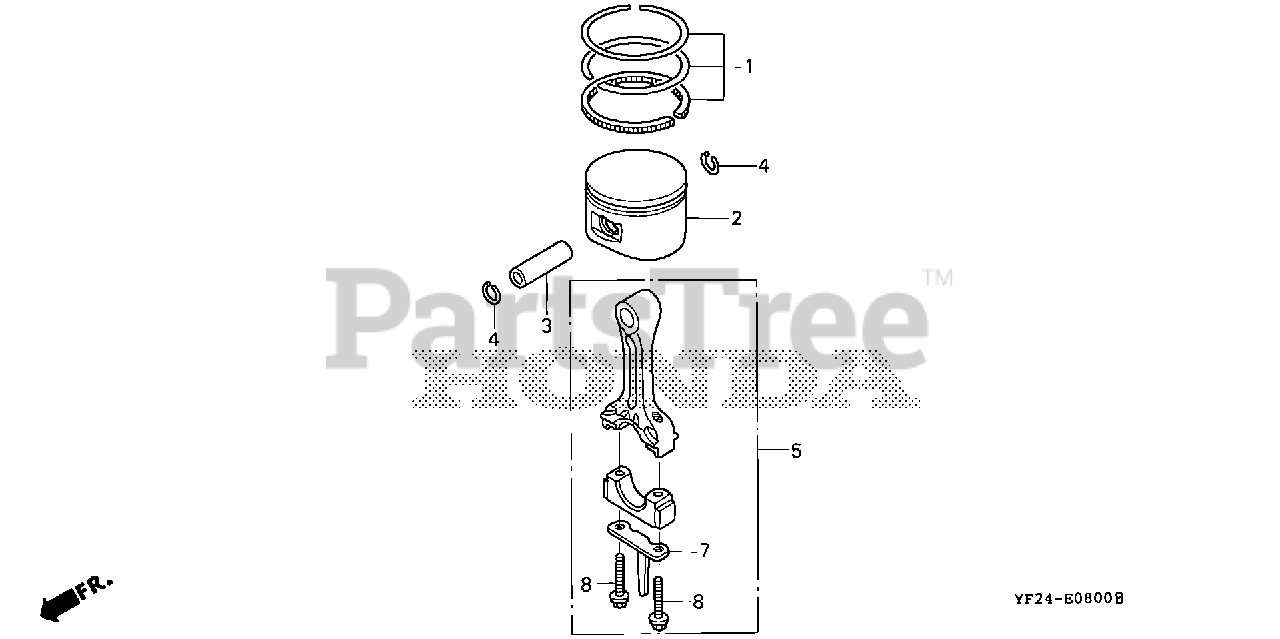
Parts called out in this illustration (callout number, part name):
1	RING SET, PISTON (STD)
2	PISTON (STD)
3	PIN, PISTON
4	CLIP, PISTON PIN (10MM)
5	ROD ASSY., CONNECTING
7	DIPPER, CONNECTING ROD
8	BOLT, CONNECTING ROD
